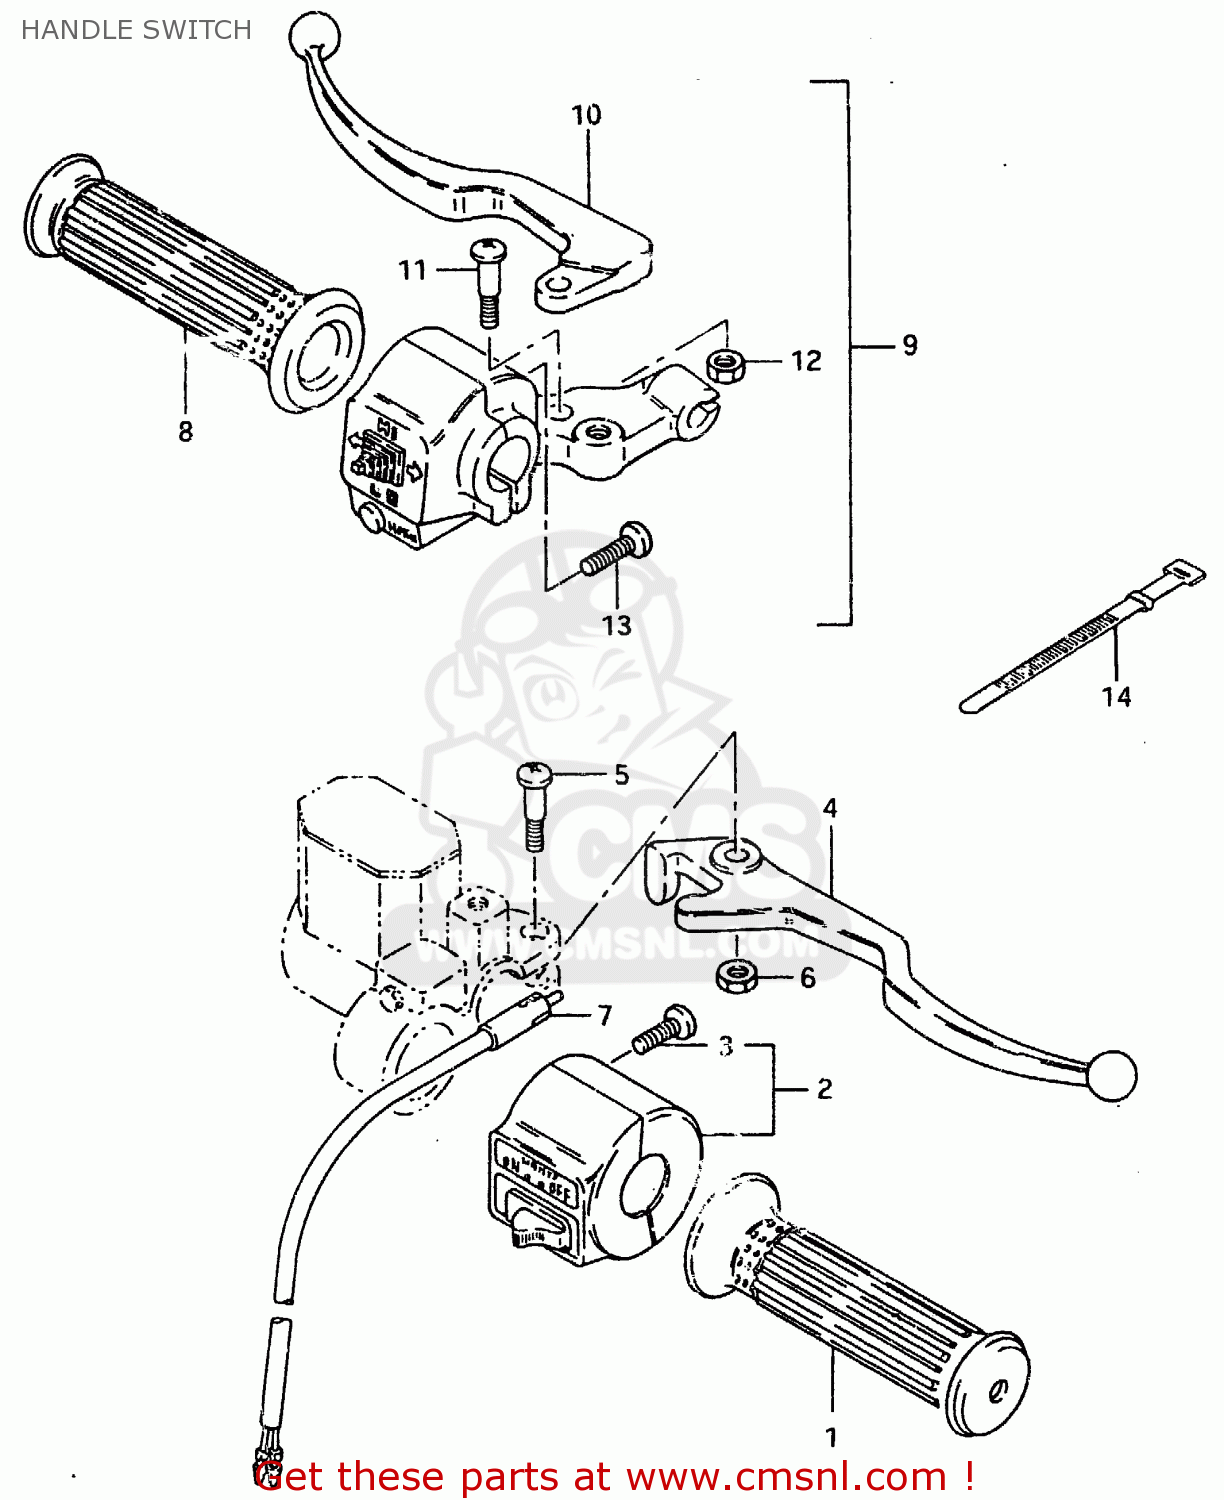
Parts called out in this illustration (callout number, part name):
1	GRIP,THROTTLE
2	SWITCH ASSY, HANDLE RH
3	SCREW 5X20
4	LEVER,BRAKE
5	SCREW
6	NUT 6MM
7	SWITCH ASSEMBLY
8	GRIP,L
9	LEVER ASSY, CLUTCH
10	LEVER,CLUTCH
11	SCREW
12	NUT,LEVER BOLT
13	SCREW 5X20
14	CLAMP(L:120)
